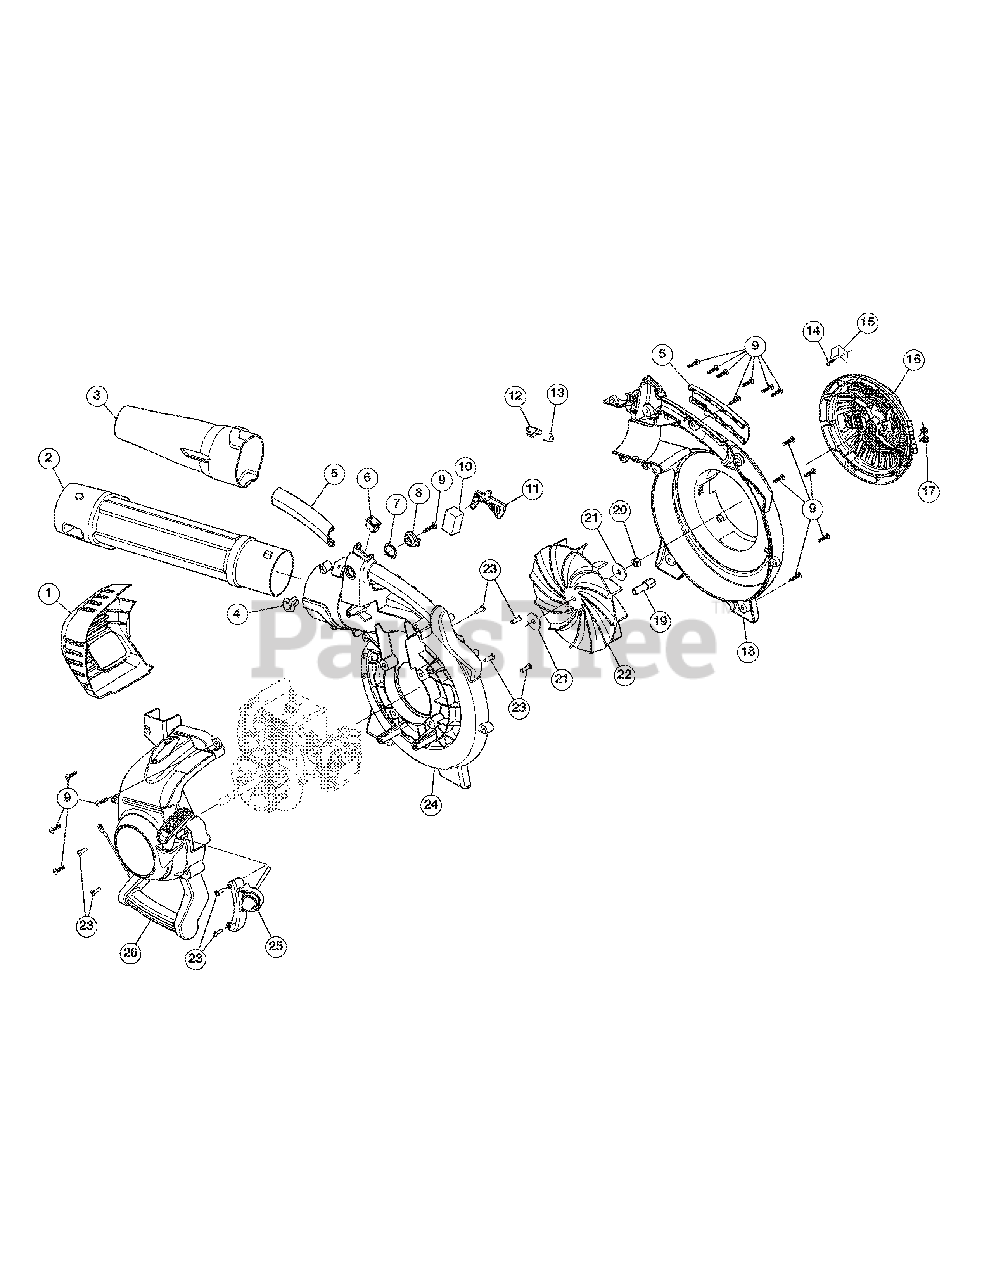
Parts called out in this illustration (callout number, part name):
1	Muffler Cover Assembly (Incl. 11)
2	Upper Tube
3	Nozzle
4	Outer Trigger Lock
5	Handle Grips
7	Wavey Washer
8	Inner Trigger Lock
10	Air Filter
11	Throttle Trigger
12	Latch Tube
13	Latch Spring
14	Screw
15	Door Lock
16	Intake Cover
17	Spring
18	Impeller Housing
19	Adapter
20	Nut
21	Washer
22	Impeller
23	Screw
24	Impeller Housing
25	Remote Primer Bracket
26	Engine Cover Assembly (Incl. 9 & 23)
